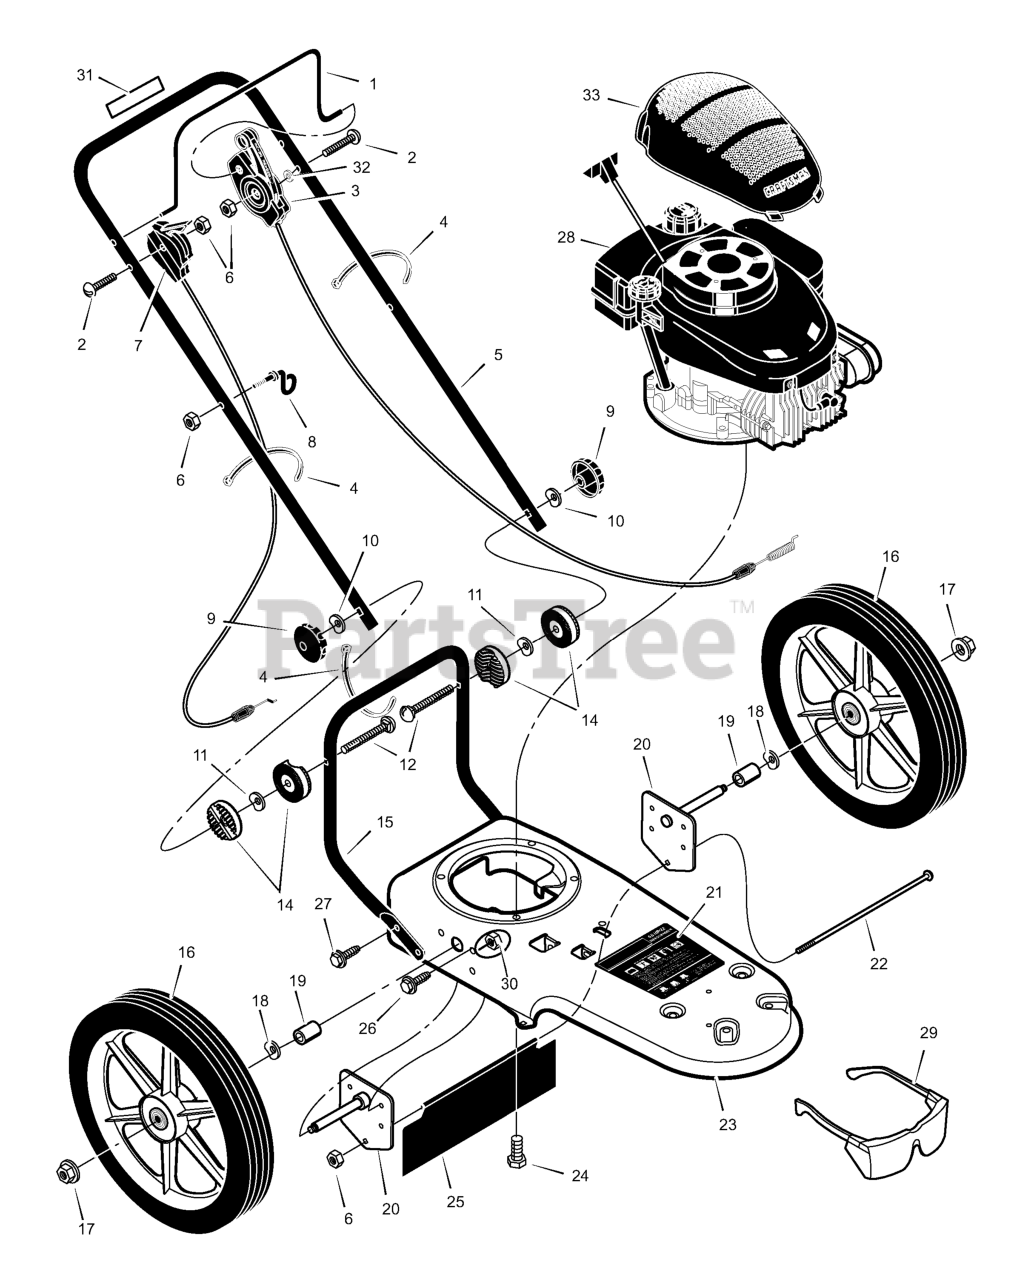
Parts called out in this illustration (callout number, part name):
1	Lever, Stop
3	Cable, Control Latching
4	Tie, Cable
7	Control, Throttle
8	Guide, Rope
9	Knob, Handle
11	Washer, Spring
14	Pivot, Handle
15	Handle, Lower
16	Wheel & Tire
17	Nut, Axle
18	Washer, Spring
20	Assembly, Axle & Bracket
22	Bolt, Carriage
23	Frame, Trimmer
25	Shield, Trailing
26	Bolt
28	Engine *
29	Protection, Eye
33	Shroud, Engine
